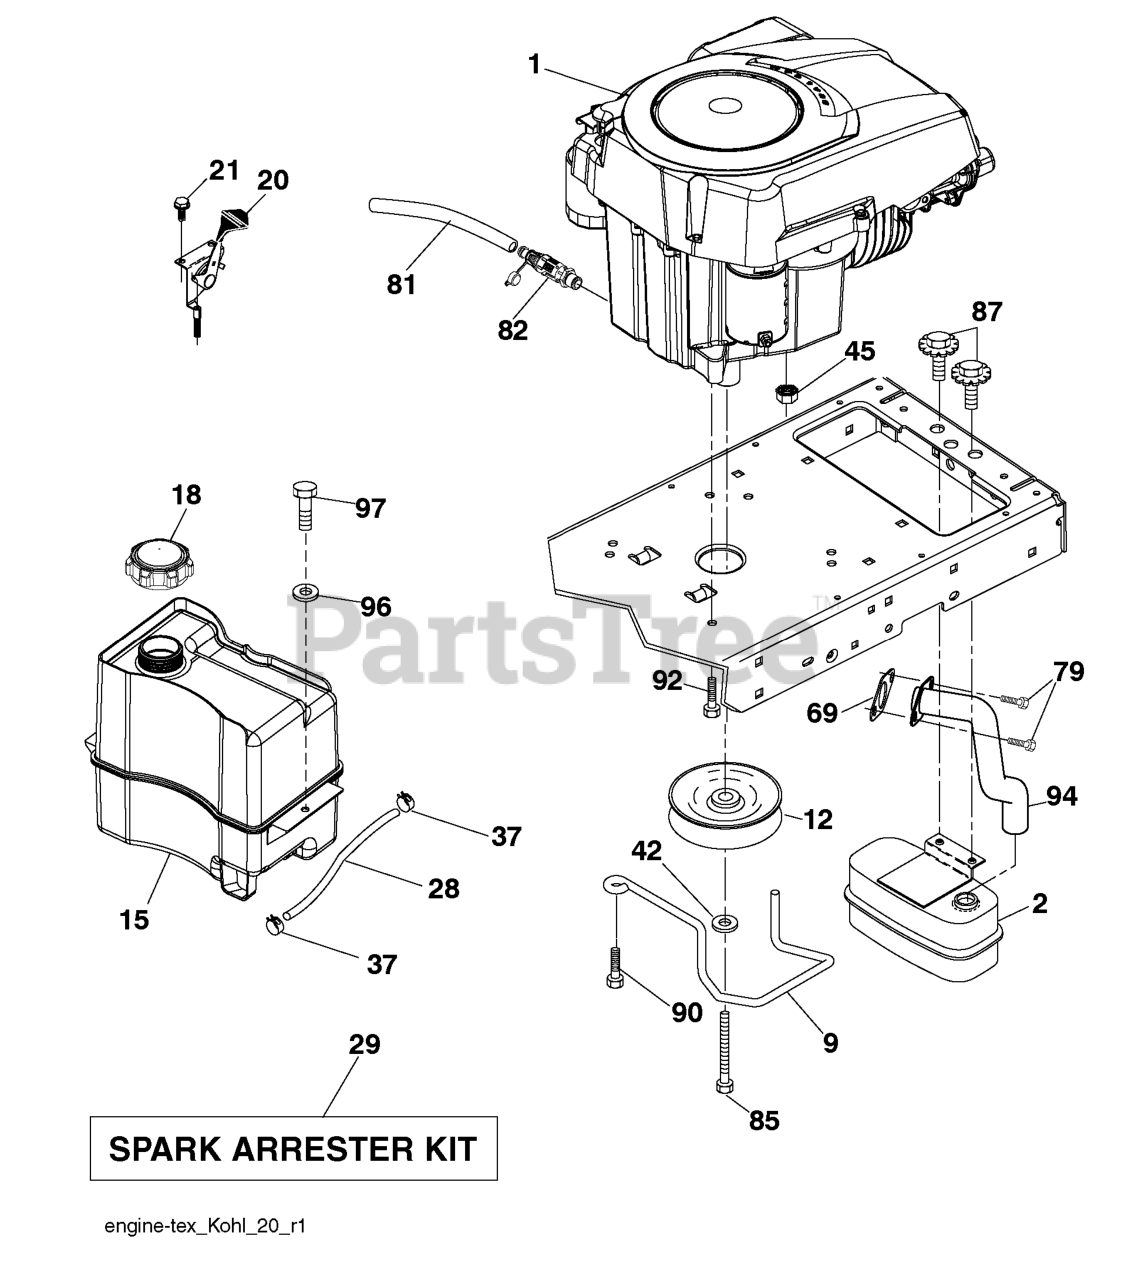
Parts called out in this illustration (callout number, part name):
2	MUFFLER.SINGLE.CYL.KOHL/B&S
9	KEEPER.BELT.ENGINE.4.2
12	RP_PULLEY ENGINE
15	TANK.ASM.FUEL.FR.2.5GA.
18	CAP ASM.FUEL.2.25"FR.
20	CONTROL.TH/CK.COBRA.KO
21	SCREW.#10 X 0.750.BOS
28	LINE.FUEL.20"FRONT.EMI
29	KIT.SPARK ARRESTOR 794945 B&S
37	HOSE CLAMP
42	LOCKWASHER
45	NUT
69	GASKET.EXHAUST.KOHLER
79	SCREW.SOCKET HD.5/16-1
81	TUBE, DRAIN OIL ASM.
82	VALUE.OIL.DRAIN
85	BOLT HEX 7/16-20X4-1/4"
87	BOLT.5/16-18UNCX3/4 W/SEMS.BLK
90	SCREW 3/8-16X1
92	SCREW 3/8-16X1
94	RP.TUBE.EXHAUST.KOHL.COURAGE
96	WASHER
97	SCREW HEXWSHR 1/4-20X3/4
